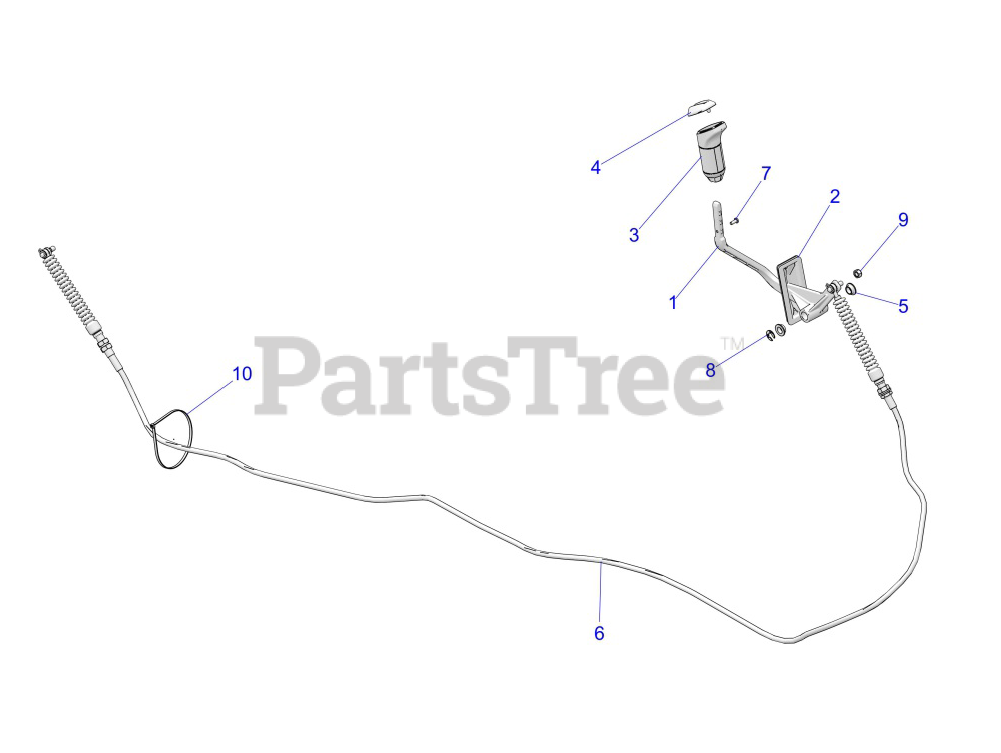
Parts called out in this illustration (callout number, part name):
1	SHIFT-LEVER,CAST,M.BLK
2	GROMMET-SHIFTER,SEALED
3	KNOB-SHIFTER,BLK
4	COVER-SHIFTER KNOB,BLK
5	BUSHING-PEDAL PIVOT
6	CABLE-SHIFTER,GAS
9	NUT,NYLOK M8X1.25(10) *
10	STRAP, PANDUIT, 14 INCH
